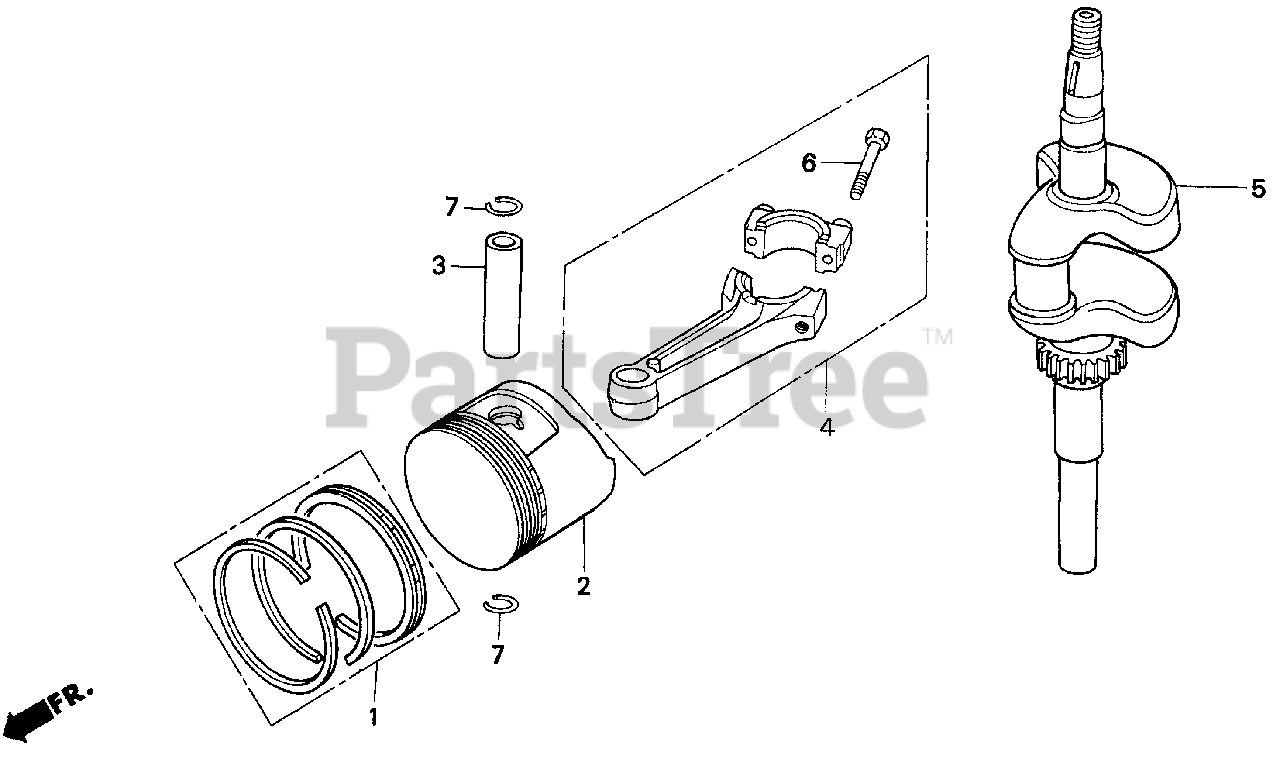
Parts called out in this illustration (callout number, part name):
1	RING SET, PISTON (STD)
1	RING SET, PISTON (OS 0.25)
1	RING SET, PISTON (OS 0.50)
1	RING SET, PISTON (0.75)
2	PISTON (STD)
2	PISTON (OS 0.25)
2	PISTON (OS 0.50)
2	PISTON (0.75)
3	PIN, PISTON
4	ROD ASSY., CONNECTING
4	ROD ASSY., CONNECTING (US 0.25)
5	CRANKSHAFT (N1 TYPE)
6	BOLT, CONNECTING ROD
7	CLIP, PISTON PIN (13MM)
